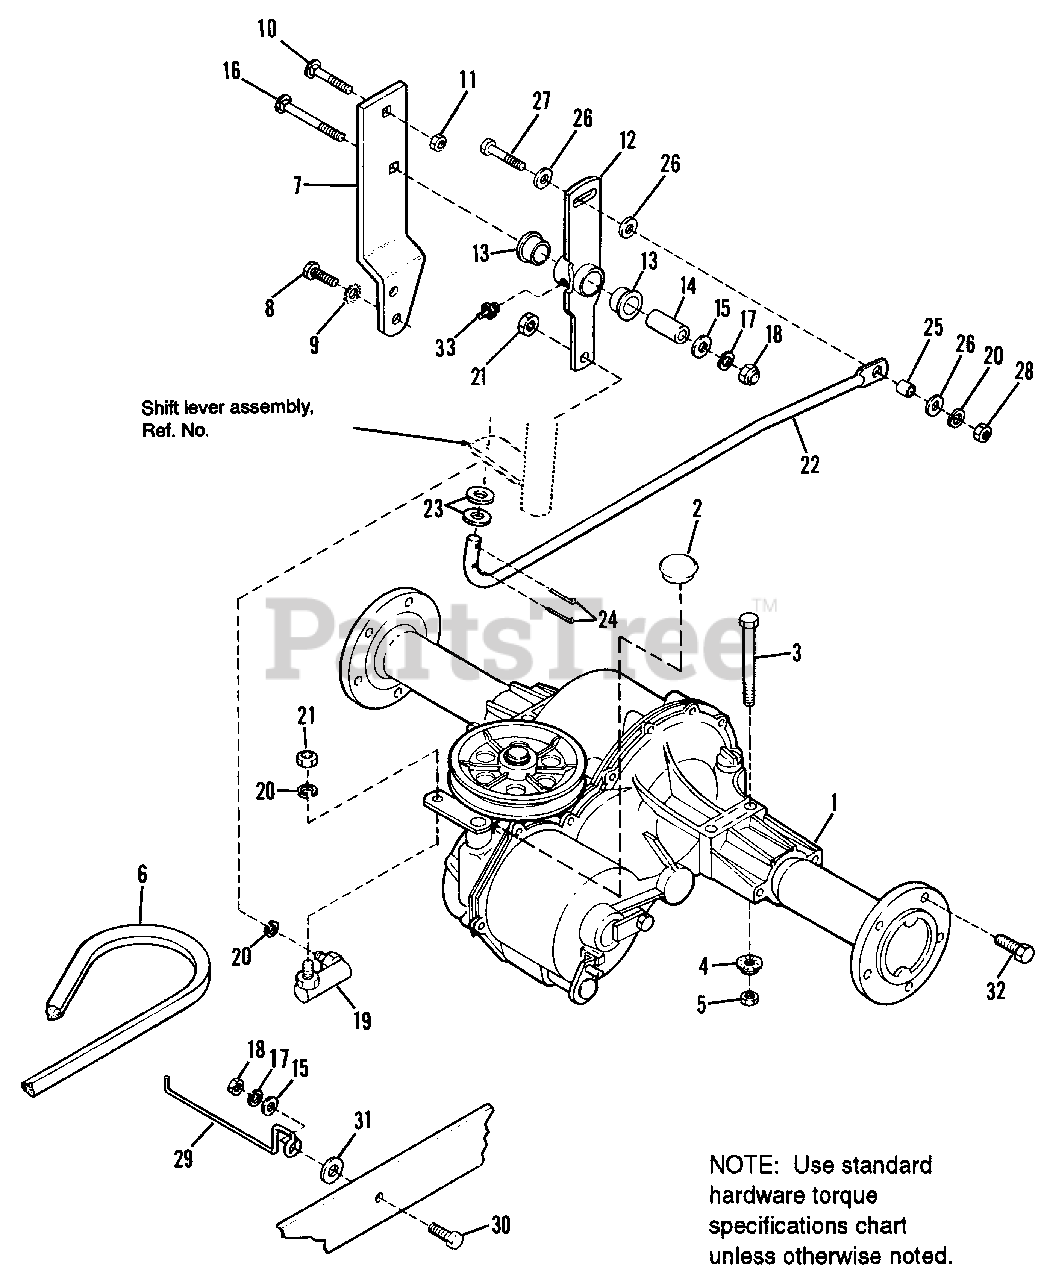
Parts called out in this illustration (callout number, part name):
1	GEAR TRANSMISSION, 6-Speed
3	CAPSCREW, Hex, 3/8-16 x 3-1/2
4	NUT, Hex, Flange Whizlock, 3/8-16
5	NUT, Hex, Jam Lock, 3/8-16
6	BELT, Drive
7	SUPPORT, Transmission
8	SCREW, Metric, M10-1.5 x 25 mm
9	LOCKWASHER External Tooth, 3/8
10	CARRIAGE BOLT, 3/8-16 x 1-1/4
11	NUT, Hex, Nyloc, 3/8-16
12	SHIFT LEVER ASSY.
15	WASHER, Flat, 3/8
16	CARRIAGE BOLT, 3/8-16 x 2
17	LOCKWASHER, 3/8
18	NUT, Hex, Full, 3/8-16
19	BALL JOINT Double-End
20	LOCKWASHER, 5/16
21	NUT, Hex, Full, 5/16-24
23	WASHER, Plain, 1/2
24	PIN, Cotter
26	WASHER, Plain, 5/16
27	SCREW, Cap, Hex, 5/16-18 x 1-1/2
28	NUT, Hex, Full, 5/16-18
30	CAPSCREW, Hex Hd., 3/8-16 x 1-1/4
31	WASHER, Plain
32	BOLT, Hub, Rear Wheel
33	GREASE FITTING
